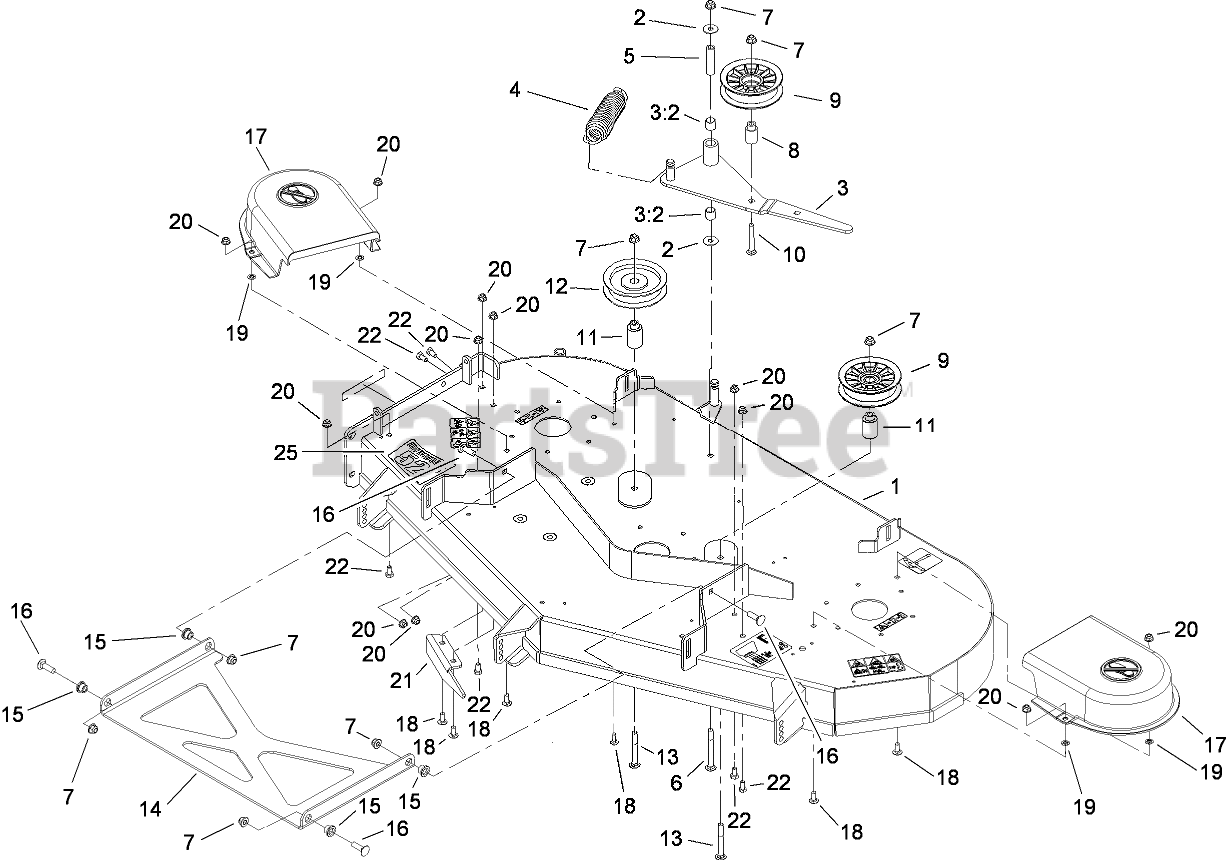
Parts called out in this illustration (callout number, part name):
1	52 INCH DECK ASM
2	WASHER
3	IDLER ARM ASM
3:2	SLEEVE-BEARING
4	Spring-Extension
5	BUSHING-PIVOT, IDLER
6	SCREW-CARR
7	NUT-HF, NI
8	BUSHING-IDLER
9	SHEAVE AND BEARING ASM
10	SCREW-CARR
11	BUSHING-IDLER
12	PULLEY-IDLER
13	BOLT-CARRIAGE
14	STRUT-DECK
15	BUSHING-FLANGED
16	BOLT-CARR
17	SHIELD-BELT
18	SCREW-CARR
19	RING-RETAINING, BOLT
20	NUT-HF, NI
21	BAFFLE-DISCHARGE
22	SCREW-HH
25	DECAL-TITAN 52 DECK
